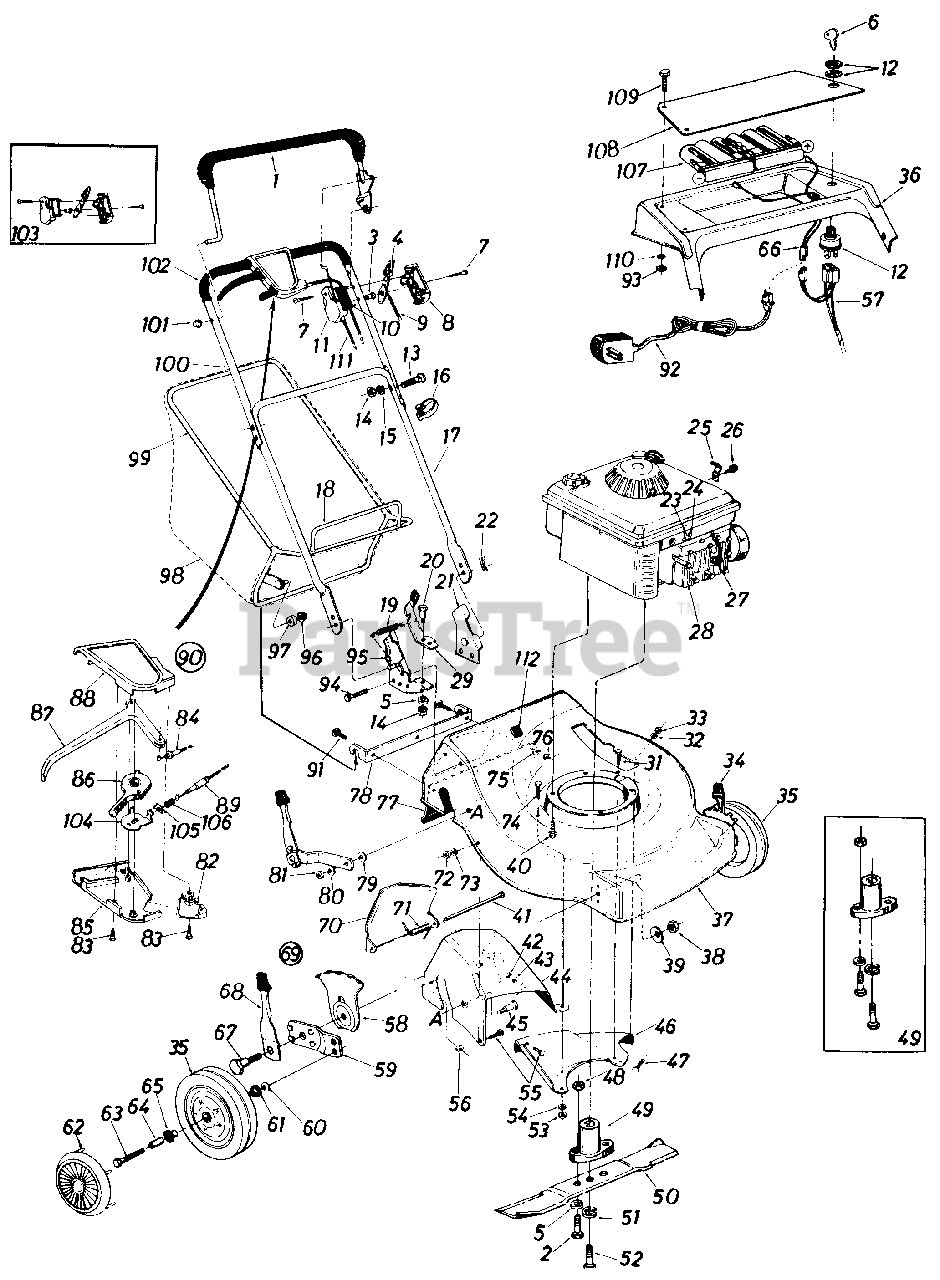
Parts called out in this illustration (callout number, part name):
1	L.H. Bail Ass'y.
2	Hex Bolt 5/16-24 x 1.00" Lg. (Grade 5)
3	Control Disc Pin
4	Throttle Control Lever
5	L-Wash. 5/16" I.D.*
6	Ignition Key
7	Truss Mach. Hi-B Tap Scr. #12 x 1.50" Lg.
8	Control Panel Half
9	Throttle Control Wire 58" Lg.
10	Control Label
11	Clutch Panel Half
12	Ignition Switch
13	Curved Carr. Bolt 5/16-18 x 1.75" Lg.
14	Hex Nut 5/16-18 Thd.*
15	L-Wash. 5/16" I.D.*
17	Lower Handle
20	Shld. Bolt .437" Dia. x .162
21	Handle Bracket Ass'y. L.H.
22	Hairpin Cotter 5/16" Dia.
23	Casing Clamp
24	Hex Sems Scr. #10-32 x .62" Lg.
25	Cable Clip
26	Hex "B"-Tap Scr. #10 x .38" Lg.
27	Spark Plug Insulator
29	L-Wash. 5/16" I.D.*
31	Hex TT-Tap Scr. 1/4-20 x .75" Lg.
32	L-Wash. 1/4" I.D.*
33	Hex Nut 1/4-20 Thd.*
34	Height Adj. Ass'y. L.H.
35	Front Wheel Ass'y. Comp. 8 x 1.75
36	Handle Panel
39	Bell-Wash. .39" I.D. x 1.38" O.D.
40	Hex Wash. Hd. TT-Tap Scr. 3/8-16 x 1.0" Lg.
42	Hex N ut 1/4-20 Thd.*
43	L-Wash. 1/4" I.D.*
44	Rear Chute R.H.
45	Shld. Bolt .500" Dia. x .685
46	Rear Baffle L.H.
47	Carr. Bolt 1/4-20 x .50" Lg.*
48	Hex Nut 5/16-24 Thd.*
49	Blade Adapter Kit
50	22" Blade
51	L-Wash. 3/8" I.D. Heavy Duty
52	Hex Bolt 3/8-24 x 2.25" Lg. (Grade 5)
53	Hex Nut 1/4-20 Thd.*
54	L-Wash. 1/4" I.D.*
55	Carr. Bolt 1/4-20 x .50" Lg.*
56	Hex Sems Nut 1/4-20 Thd.
57	Wire Harness
58	Height Adj. Plate
59	Wheel Pivot Bar
60	Bell-Wash. .40" I.D. x .88" O.D.
61	Flg. Ball Brg. 3/8" I.D.
62	Plastic Hub Cap
63	Hex Bolt 3/8-16 x 1.75" Lg.
64	Spacer .375" I.D. x .505" O.D.
65	Flg. Ball Brg. 1/2" I.D.
66	Battery Pack Lead
67	Shld. Bolt .50" Dia. x .430
68	Spring Lever Ass'y. w/ Knob
69	Height Adj. Ass'y. R.H.
70	Chute Door
71	Torsion Spring
72	Hex Nut 1/4-20 Thd.*
73	L-Wash. 1/4" I.D.*
74	Hex Bolt 1/4-20 x .88" Lg.
75	Fl-Wash. .285" I.D. x 1.25" O.D.
76	Hex Sems Nut 1/4-20 Thd.
78	Grass Catcher Hitch Brkt.
79	Bell-Wash. .400" I.D. x 1.13" O.D.
80	Bell-Wash. .400" I.D. x .88" O.D.
81	Hex Jam Nut 3/8-16 Thd.
82	Cable Mounting Cap
83	Flat "C"-Sunk Hd. Tap Scr. #10 x .75" Lg.
84	S.P. Cable x 53" Lg.
85	3-Sp. S.P. Control Lower Cover
86	Shimano 3-Sp. Shift Lever
87	Control Lever
88	3-Sp. S.P. Control Upper Cover
89	Shimano 3-Sp. Solid Shift Cable
90	Clutch Control Housing Comp.
91	Carr. Bolt 1/4-20 x .75" Lg.*
92	Battery Charger
93	Hex Nut #8-32 Thd.
94	Hex Bolt 1/4-28 x .75" Lg.*
95	Handle Bracket Ass'y. R.H.
96	Push Nut 3/8" Rod
97	Plastic Roller
98	Grass Bag
99	Catcher Upper Frame
100	Upper Handle
101	Cap Speed Nut
102	Grip
103	Control Housing Comp.
104	Shimano 3-Sp. Shift Lever Brkt.
105	Shimano 3-Sp. Cable Spring Brkt.
106	Shimano 3-Sp. Cable Mounting Spring
107	Battery Pack
108	Battery Plate
109	Fl-Hd. Phil. Scr. #8-32 x .38" Lg.
110	External L-Wash. #8 I.D.
111	Clutch Control Cable 45" Lg.
8366-190-5	Hardware Pack
